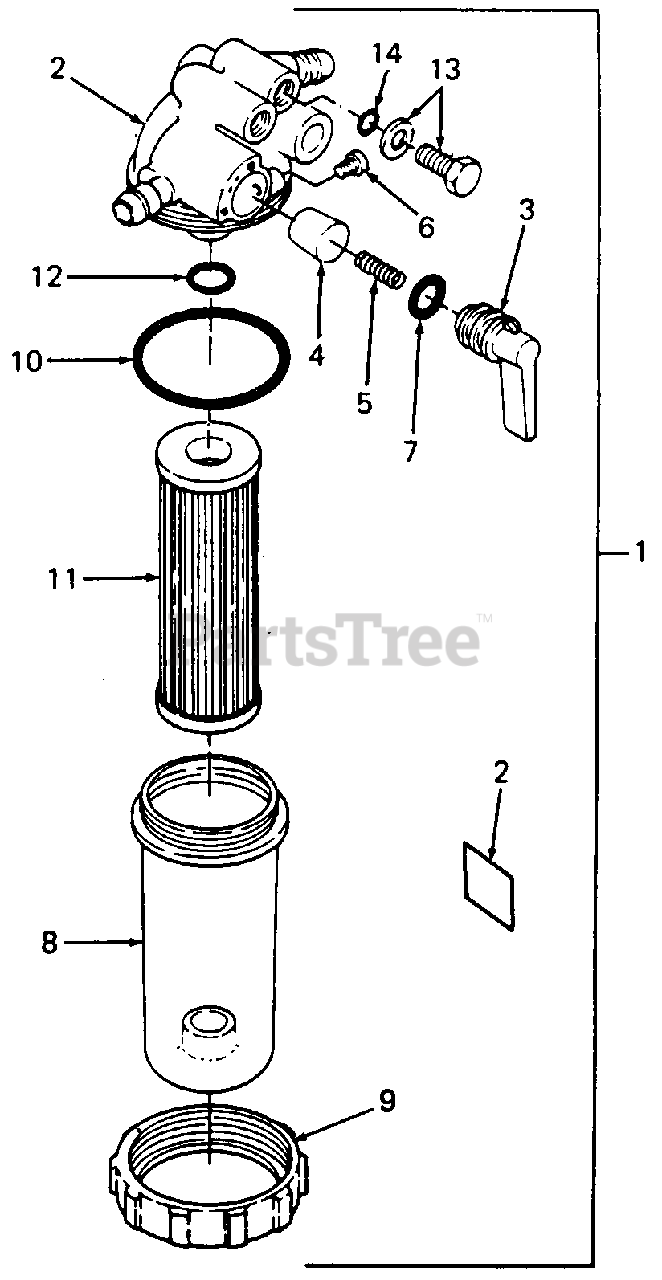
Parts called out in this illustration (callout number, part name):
1	Filter, Fuel
5	Spring, Valve
7	O-Ring, Lever
8	Cup, Filter
10	O-Ring, Filter Cup
11	Element
12	O-Ring, Filter
13	Plug, Breather
